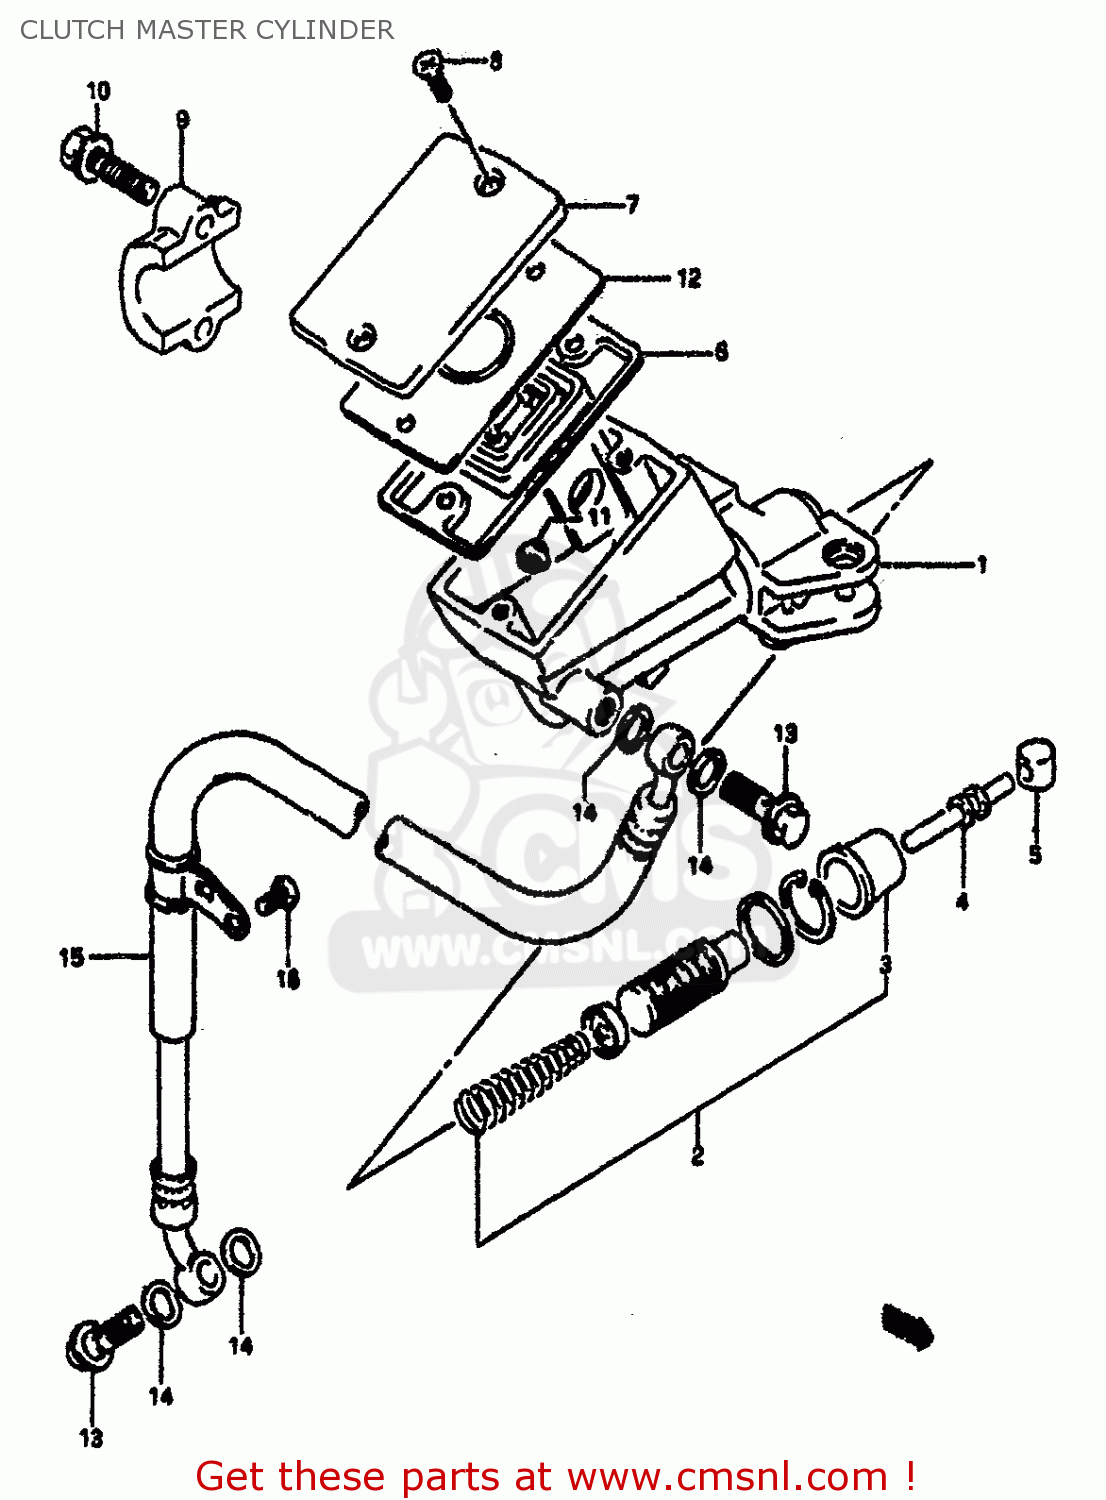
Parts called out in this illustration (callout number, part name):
1	CYLINDER ASSEMBLY,CLUTCH MASTER
2	PISTON & CUP SET
3	BOOT
4	ROD,PUSH
5	BUSH
6	7
7	CAP
8	SCREW
9	HOLDER
10	BOLT
11	PROTECTOR
12	PLATE,DIAPHRAGM
13	BOLT UNION
14	WASHER(10X15X1.5)
15	HOSE,CLUTCH
16	SCREW
